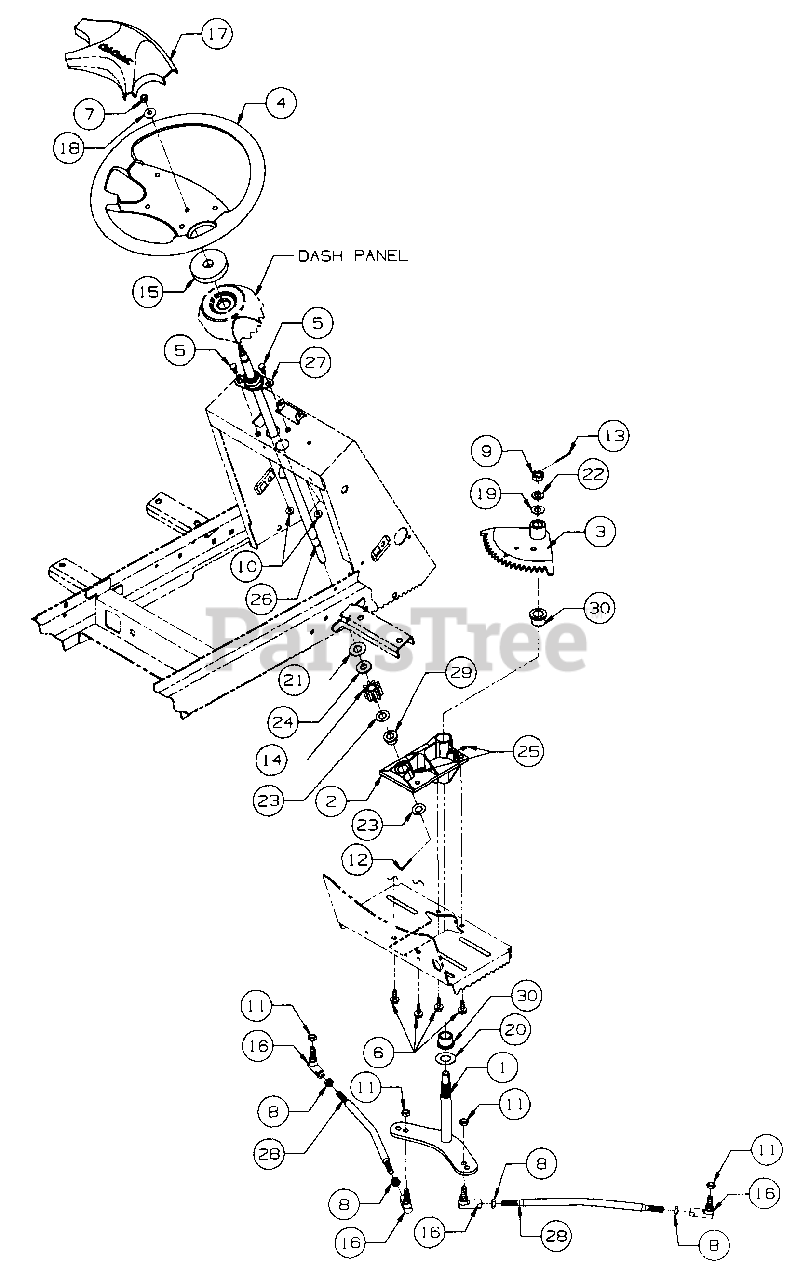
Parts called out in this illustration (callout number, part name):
1	Arm Assy, Lower Steering
2	Housing Assy, Steering
3	Segment Assy, 18T - Steering
4	Wheel, Steering
5	Screw, Hex Cap, 1/4-20 x .62 Lg
6	Screw, Hex Wash Sf-Tapp 5/16-18 x .75 Lg
7	Nut, Hex Center Lock, 5/16-24
8	Nut, Hex Jam, 3/8-24 GR5
9	Nut, Hex Slotted, 1/2-20 GR5
10	Nut, Hex Flange Lock, 1/4-20
11	Nut, Hex Lock, 3/8-24 GR5
12	Pin, Cotter, 1/8 Dia x 1.0 Lg
13	Pin, Cotter, 3/32 Dia x 1.25 Lg
14	Pinion, Steering
15	Gasket, Steering
16	Joint, Ball, 3/8-24
17	Insert, Steering Wheel, Cub Cadet
18	Washer, Bell, .340 x .88 x .06 Thk
19	Washer, Flat, .510 x 1.0 x .06 Thk
20	Washer, Flat, .760 x 1.50 x .030 Thk
21	Washer, Flat, .56 x 1.0 x .040 Thk
22	Washer, Lock, 1/2
23	Washer, Flat, .531 x 1.0 x .027 Thk
24	Washer, Rubber Flat, .50 x 1.12 x .125 Thk
25	Fitting, Lube, 3/16 Drive Type
26	Shaft, Steering
27	Bearing, Flange
29	Bearing, Flange, .503 ID
30	Bearing, Bronze Flange, .75 ID
